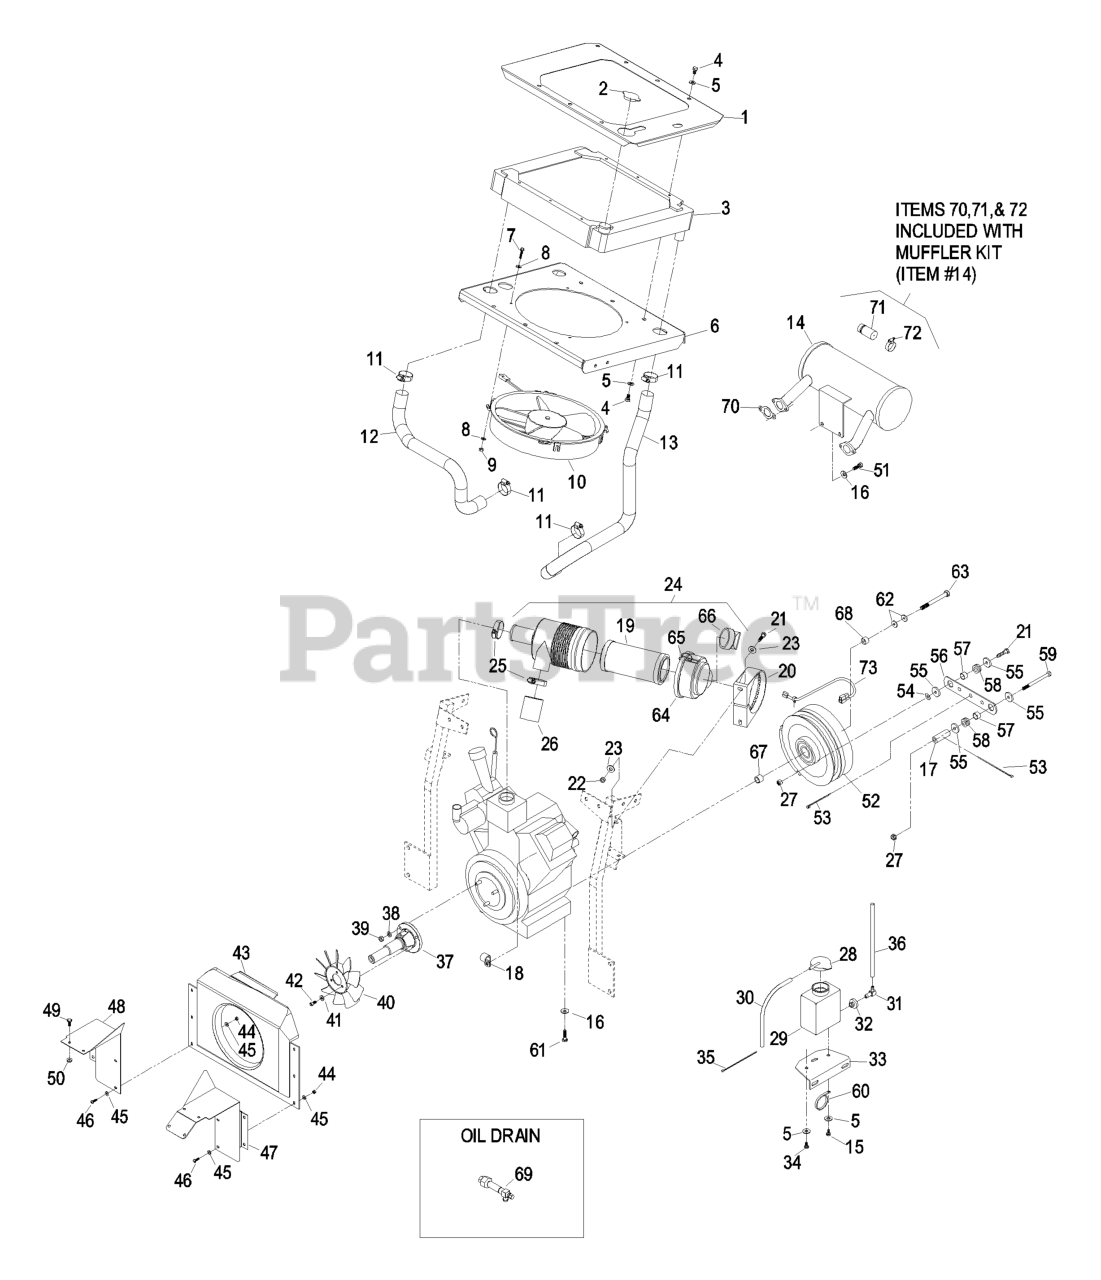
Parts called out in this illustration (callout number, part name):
2	CAP-RADIATOR
3	RADIATOR-MOUNT
4	SCREW-HH
5	WASHER-PLAIN
8	WASHER-FLAT
9	NUT-LOCK, HH
12	HOSE-INLET, RADIATOR
13	HOSE-OUTLET, RADIATOR
14	KIT,MUFFLER W/ARRESTOR
15	SCREW-HH
16	WASHER-BELLEVILLE
17	SPACER-ANCHOR, CLUTCH
18	CLIP-LOOM
20	BRACKET-MOUNTING
21	SCREW-HH
22	NUT-LOCK, NI
23	WASHER-FLAT
24	AIR CLEANER ASM
25	CLAMP-HOSE
26	HOSE-INLET, AIR
28	CAP-TANK, OVERFLOW
29	TANK-OVERFLOW
33	BRACKET-BOTTLE
34	SCREW-HH
35	TIE-CABLE
37	EXTENSION-CRANKSHAFT
38	WASHER-LOCK
39	NUT-HEX
40	FAN-PUMP, COOLING
41	WASHER-FLAT
42	SCREW-HSH
43	SHROUD-FAN, HYD
44	NUT-LOCK, NI
45	WASHER-FLAT
46	SCREW-PPH
47	SHIELD-LH
49	SCREW-HH
51	SCREW-HH
53	TIE-PLASTIC
54	WASHER-FLAT
56	STRAP-CLUTCH, BRAKE
58	GROMMET
59	SCREW-HH
60	CLIP-LOOM
61	SCREW-HH
62	WASHER-SPRING
63	SCREW-HH
64	COVER ASM
65	LATCH-CLEANER, AIR
66	VALVE-VACUATOR
67	SPACER-CLUTCH
68	KEEPER-CLUTCH
69	VALVE-DRAIN, OIL
70	GASKET-EXHAUST
71	ARRESTOR-SPARK
72	CLAMP-MUFFLER
73	KIT,CLUTCH JUMPER HARNESS
